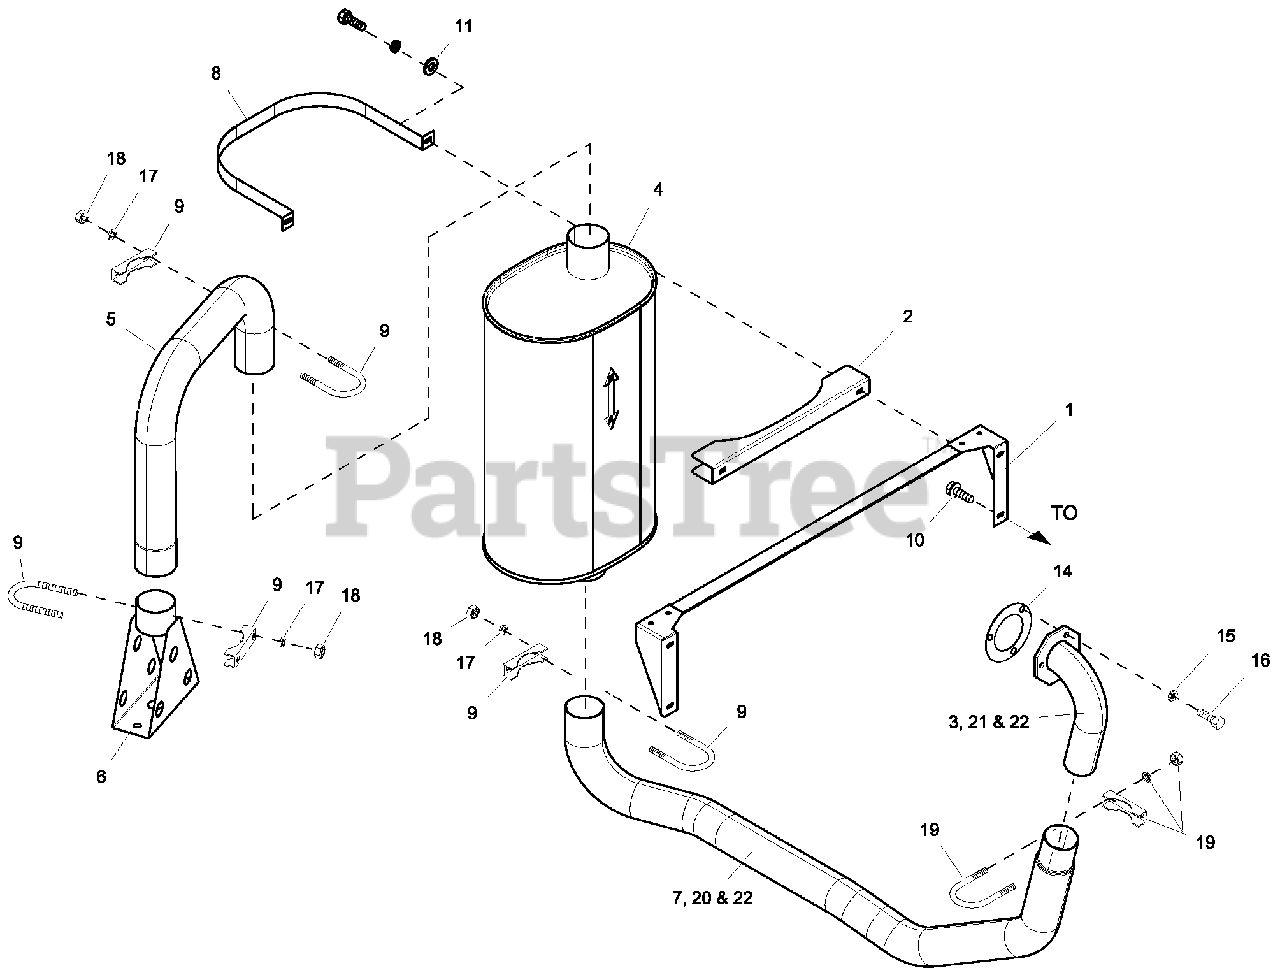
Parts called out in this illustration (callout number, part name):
1	REAR WRAP C2 CPL
2	SCREW THF M6-1 X 16 N WA Z/JS
3	DOOR C2
4	RIVET POP.1875 X .450 SS
5	SCREW TH-FRM M6 W/CAP SHKPRF W
6	DUCT DISCHARGE LH C2 AL
7	FRONT CORNERS C2
8	DUCT DISCHARGE MI D C2
9	NUT HEX M 6X1.0 G8 YELCHR
10	NUT HEX LOCK M6-1.0 SS NY INS
11	ROOF C2 CPL PVT LBL
12	SLITTER C4
13	SPLITTER LOWER C4
14	SPLITTER STRINGER C2
15	SUPPORT SPLITTER LHC2
16	PULL TAB DOOR LOCK SS
17	ASSEMBLY COVER ACCESS
18	WASHER FLAT 1/4-M6 ZINC
19	WASHER LOCK M6-1/4
20	NUT HEX 1/4-20 STEEL
21	INSULATION RETAINMENT HANGER
22	WASHER SELF LOCKING DOME #4-40
23	INSULATION DOOR C2
24	INSULATION ROOF TOP
25	VISE-ACTION LATCH SLOTTED CIR
26	GASKET EXTRUDED TRIM (328" LG)
27	INSULATION SPLITTER
28	INSULATION SPLITTER
29	INSULATION DUCT
30	RETAINER INSULATION (820)
31	INSULATION DUCT SIDES
32	RETAINER INSULATION (450)
33	WASHER SELF LOCKING DOME #8-32
34	INSULATION LOWER SPLITTER
35	SCREW HHC M6-1.0X20 G8.8
36	ASSY WIRE 14 AWG 34.8" GRN/YEL
37	WASHER SHAKEPROOF INT 1/4
38	TAPE FOAM 1X1 (150" LG)
39	KEY VISE-ACTION LATCH SLOT CIR
40	FOAM 300 X 300 THERMAL ACO (APPLIES TO 4.2L UNITS ONLY)
41	STRIP SEALANT 1/8X 1 (44.52+LG)
42	RF COVER PLATE-PLASTIC- D RK GRY (OPTIONAL)
43	DUCT DISCHARGE RH C2 AL
44	ASSY ENCLOSURE GEN SIDE RF
45	SCREW PPPH M3X12
46	WASHER FLAT M3
47	BADGE, HONEYWELL
48	BAFFLE TOP EXHAUST C2 HW
49	DEFLECTOR INTAKE 2.4L G2 TURBO
50	NUT UM6-1.0 GEOMET
51	SCREW HHFC M6-1.0X 2 0 G8.8
